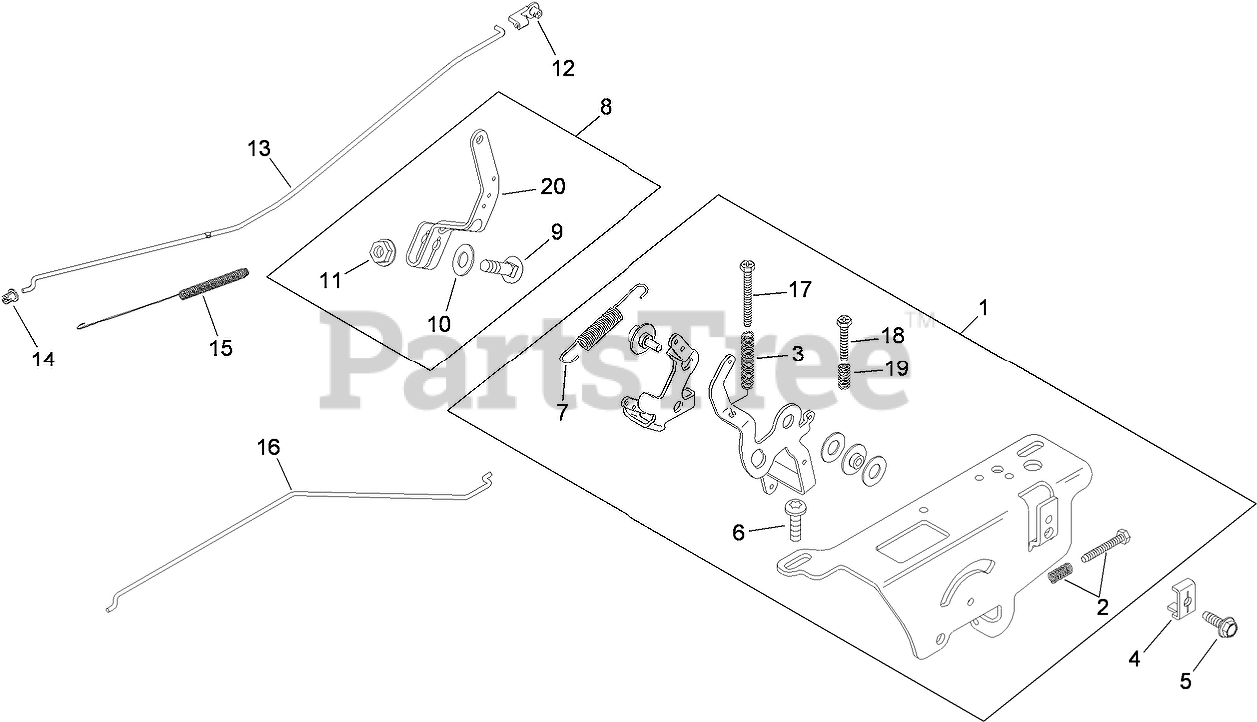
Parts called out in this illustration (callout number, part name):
1	SPEED CONTROL ASM (INCLUDES REF 2, 3, 6 QTY 1], 7, 17-19)
2	IDLE ADJUSTING SCREW AND SPRING KIT
3	SPRING-CONTROL, SPEED (LONG)
4	CLAMP-CABLE
5	SCREW-FLANGE, THREAD FORMING (M5X0.8X16)
6	Screw-Socket, 6 Lobed (Thread Forming, M6x1.0x20)
7	Spring-Governor
8	GOVERNOR LEVER ASM (INCLUDES 9-11, 20)
9	Bolt-Square Neck, Round Head (1/4-20x1)
10	Washer-Lock, Internal Tooth (1/4)
11	Nut-Flange, Hex (1/4-20)
12	BUSHING-RETAINING, LINKAGE
13	LINKAGE-THROTTLE
14	BUSHING-LINKAGE, THROTTLE
15	Spring-Linkage
16	Linkage-Choke (Single Wire)
17	SCREW-PHL THD FRM (M4X0.7X38)
18	Screw-Thread Forming (M4x0.7x25)
19	Spring-Control, Speed
20	Lever-Governor
